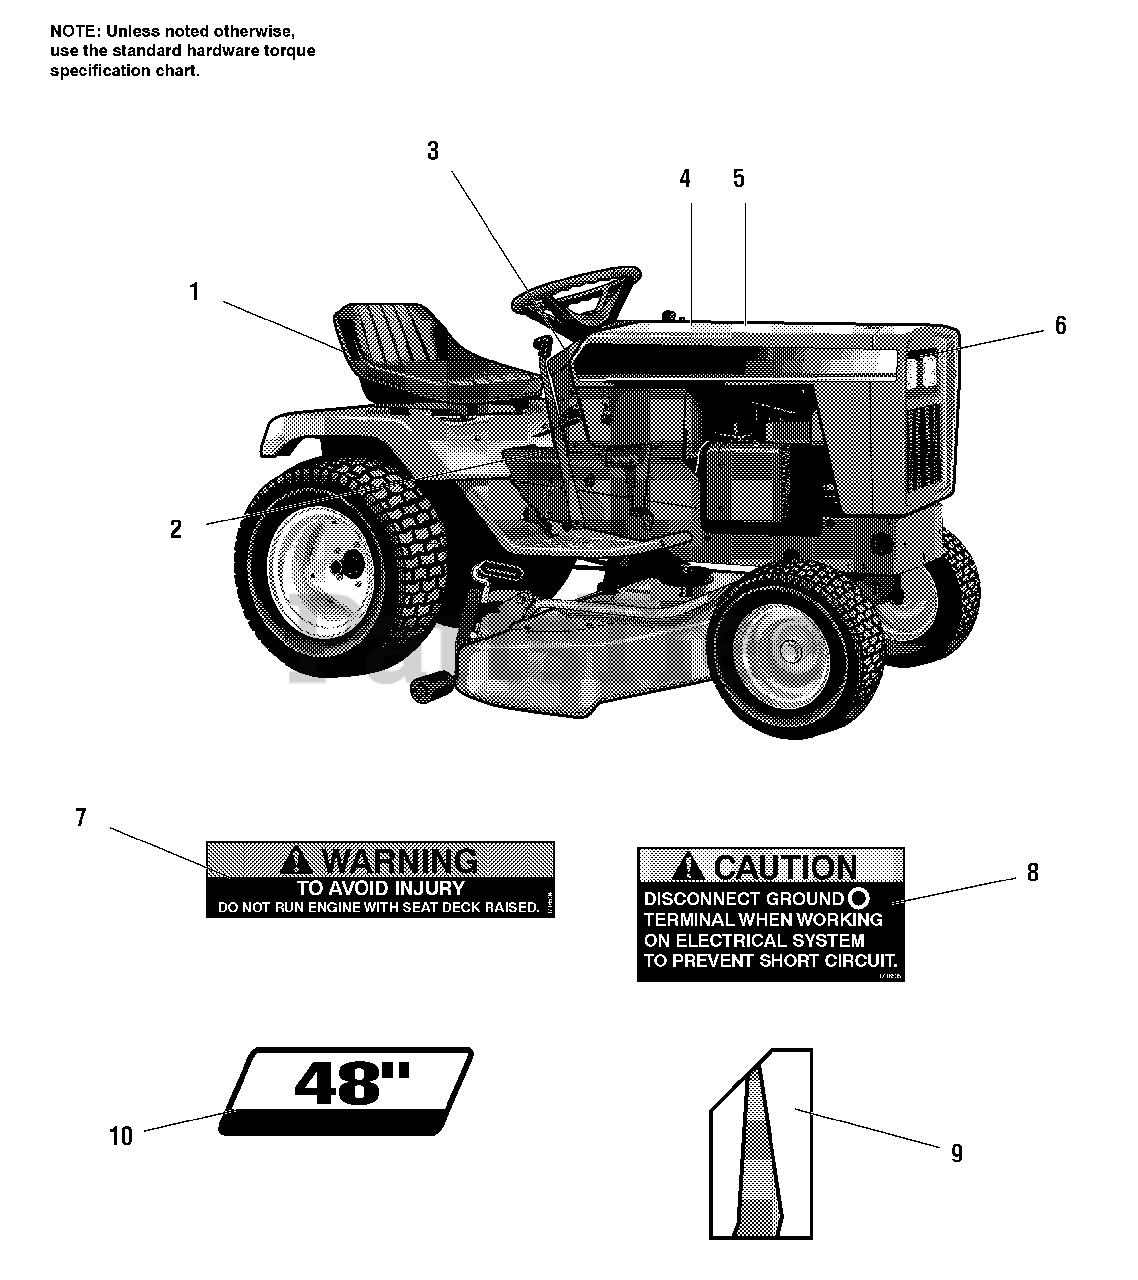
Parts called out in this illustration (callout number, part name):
1	DECAL, USA
2	DECAL, Console
3	DECAL, Dashboard
4	DECAL, Touch-Up Paint (Orange)
4	DECAL, Touch-Up Paint (Red)
4	DECAL, Touch-Up Paint
5	DECAL, Belts & Blades
6	DECAL, Grill
7	DECAL, Warning
8	DECAL, Caution
9	DECAL, Belt Adjustment
10	DECAL, Cutting Width
